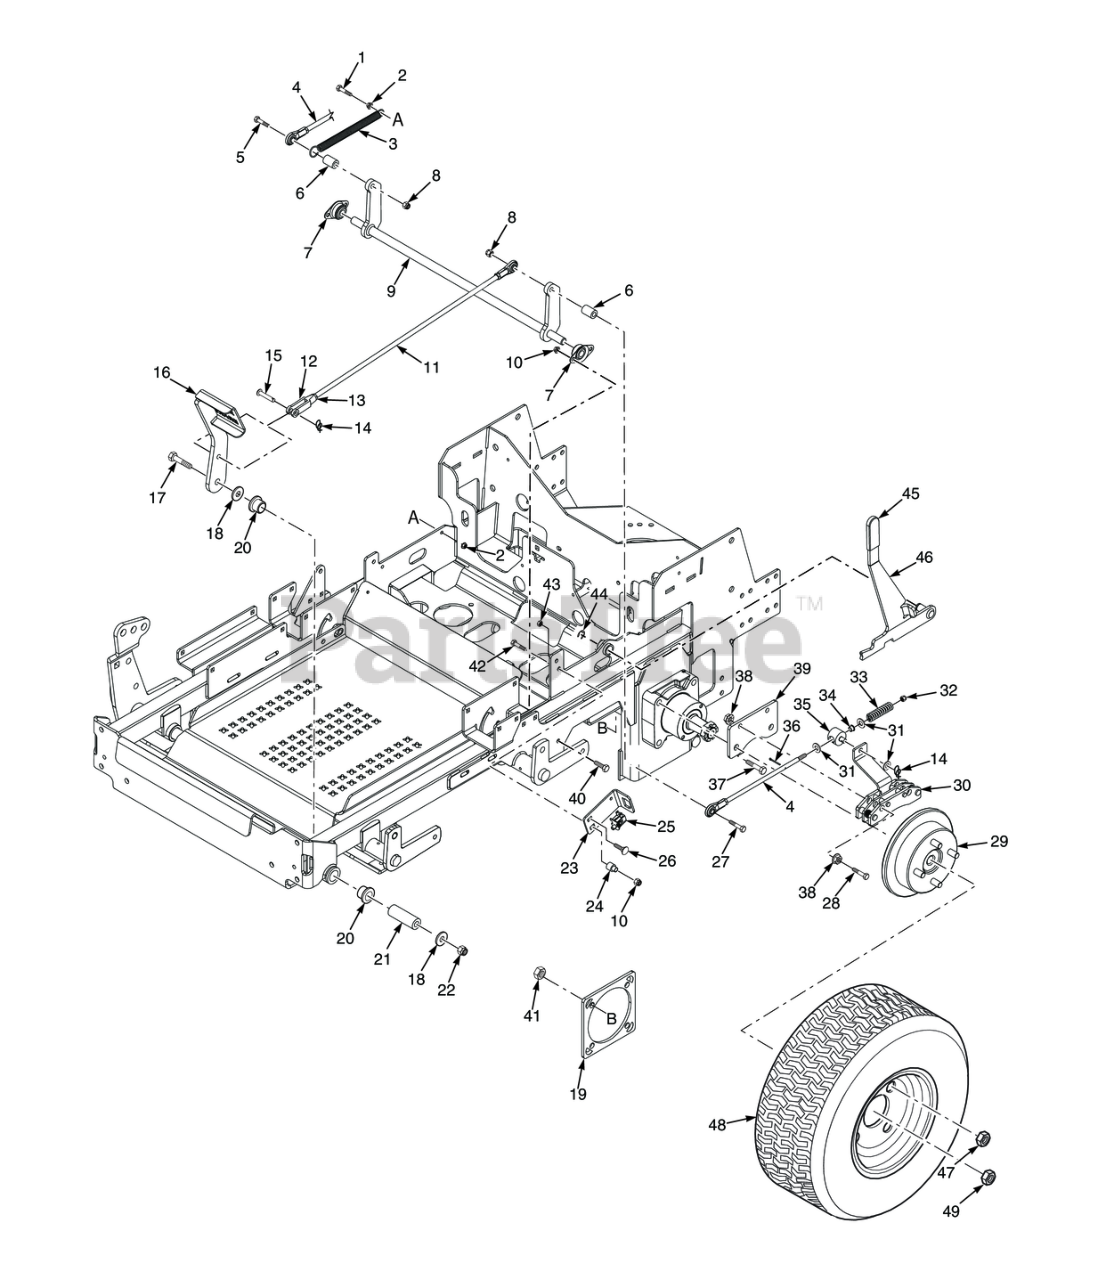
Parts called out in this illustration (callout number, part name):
1	SERR. FLG. HEX HEAD CAPSCREW, 5/16-18 X 3/4
2	NUT, 1/4-20 SERRATED FLANGE HEX HEAD
3	Spring, Brake Return
4	Brake Link Assembly
5	Bolt, Hex Head 3/8-16 x 3" - 52"
6	Spacer
7	Bearing, Self Aligning - 5/8 I.D.
8	Nut, Flange Elastic Stop Nut, 3/8-16
9	Brake Bellcrank Weldment
10	HEX NUT, ELASTIC STOP LOCK, 5/16-18
11	Brake Rod Assembly
12	Clevis, Traction Control
13	Nut, 3/8-24 UNF R.H. Thread
14	Pin, Rue Cotter 3/8" Diameter
15	Pin, Clevis 3/8-16 x 1-1/16"
16	Brake Pedal Weldment
17	Bolt, Hex Head 1/2-13 x 4-1/4"
18	Flat Washer, 1/2 (.562 x 1.375 x .109)
19	Plate Weldment, Motor Backing
20	Bearing, Plastic
21	Sleeve, Brake Pivot
22	HEX LOCKNUT, ELASTIC STOP, 1/2-13
23	Switch Mounting Bracket, Brake
24	Spacer, Pump Dampener
25	Switch, Interlock, Normally Open
26	Serr. Fl. Hex Head CPSCR, 1/4-20 x 3/4"
27	Bolt, Hex Head 3/8-16 x 3" - 52"
28	Bolt, Hex Head 1/2-13 x 4" (lower)
29	Wheel Hub w/Disc
30	Brake Caliper
31	Flatwasher, 3/8 (.406 x .812 x .065)
32	Nut, Elastic Stop 3/8-16, grade 8 black
33	Spring, Brake
34	Bearing
35	Swivel Assembly, Brake
36	Pin, Cotter 3/32 x .75"
37	Bolt, Hex Head 1/2-13 x 2-3/4" (48V & 52V - One Weight)
38	Nut, Hex Serrated Flange 1/2-13
39	Mounting Bracket, Brake
40	BOLT, SERRATED FLANGE HEX HEAD 5/16-18 X 3/4"
41	Locknut, Hex 1/2-13 Center Lock
42	Bolt, Hex Head 5/16-18 x 1-1/2" - Front
43	HEX, NUT, ELASTIC STOP LOCK, 1/4-20
44	RETAINING RING, 5/8" EXTERNAL "E"
45	Grip, Brake Handle
46	Lever w/Grip, Parking Brake
47	Wheel Nut, 1/2-20 x 13/16
48	Wheel Assy 24 x 9.5-12 (48" Deck)
49	Nut, Hex Castle 1.0-20 UNEF
